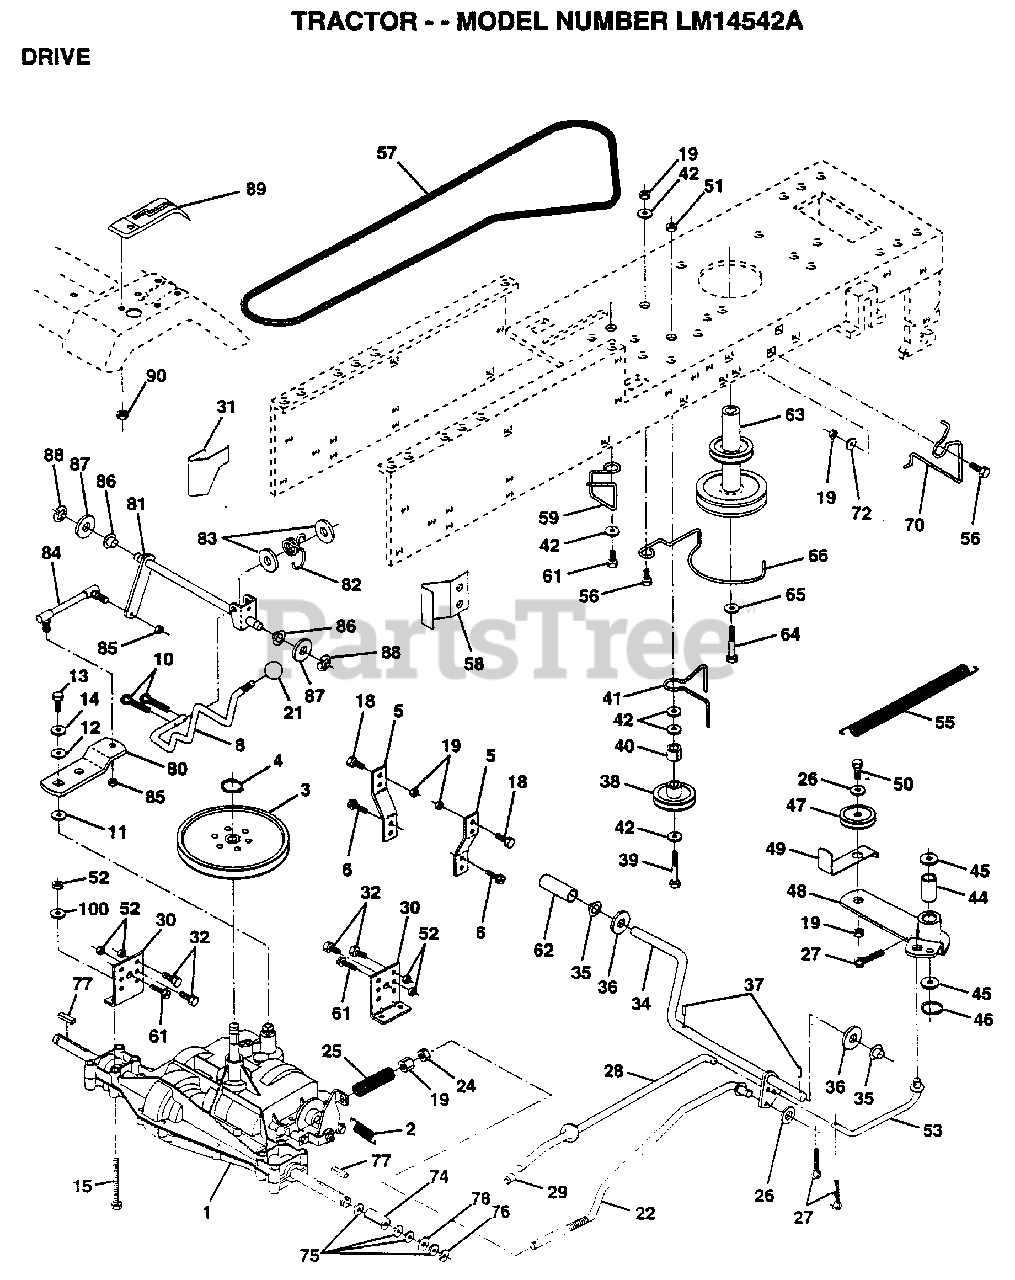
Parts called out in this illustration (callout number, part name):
2	SPRING.BRAKE.RETU
3	PULLEY TRANS
5	STRAP TORQUE
6	SCREW
8	ROD SHIFT FEND LT
10	PIN COTTER 1/8
11	WASH-SHFT PLT LT
12	WASHER
13	BOLT.1/4-28.W/PAT
14	LOCKWASHER
15	BOLT HEX
18	BOLT
19	NUT
21	KNOB T (1/2-HOLE)
22	BRAKE ROD
24	NUT
25	SPRING ROD LT
26	WASHER
27	COTTER PIN
28	ROD.BRAKE.PARK.LT
29	PLUNGER CAP T
30	TRANSAXLE MTG BKT
31	"KEEPER,BELT LH T"
32	BOLT
34	SHAFT.PEDAL.FOOT
35	NYLON BEARING
36	WASHER LT
38	PULLEY.IDLER.FLAT
39	BOLT
40	SPACER T
41	BELT KEEPER LT
42	WASHER
44	"LY, BEARING"
45	WASHER LT
46	KLIP RING
48	ARM IDLER
49	RETAIN BELT
53	"LINK, CLUTCH T"
55	"SPRING, RETURN LT"
58	"KEEPER,BELT RH T"
59	KEEPER BELT CNTSP
61	SCREW
62	PEDAL COVER T
63	PULLEY.ENGINE
64	BOLT
65	LOCKWASHER
66	KEEPER.BELT.ENG.L
70	KEEPER BELT ENG
72	WASHER
74	SPACER LT
75	WASHER
76	E-RING LT
77	SQUARE KEY
78	WASHER
80	SHIFT LEVER
81	SHAFT ASM SHIFT
82	"SPRING,TORSION"
83	WASHER
84	TIE ROD
85	NUT 1/4-28
86	BUSHING
87	WASHER D
88	KLIP RING
90	NUT
100	WASHER M
